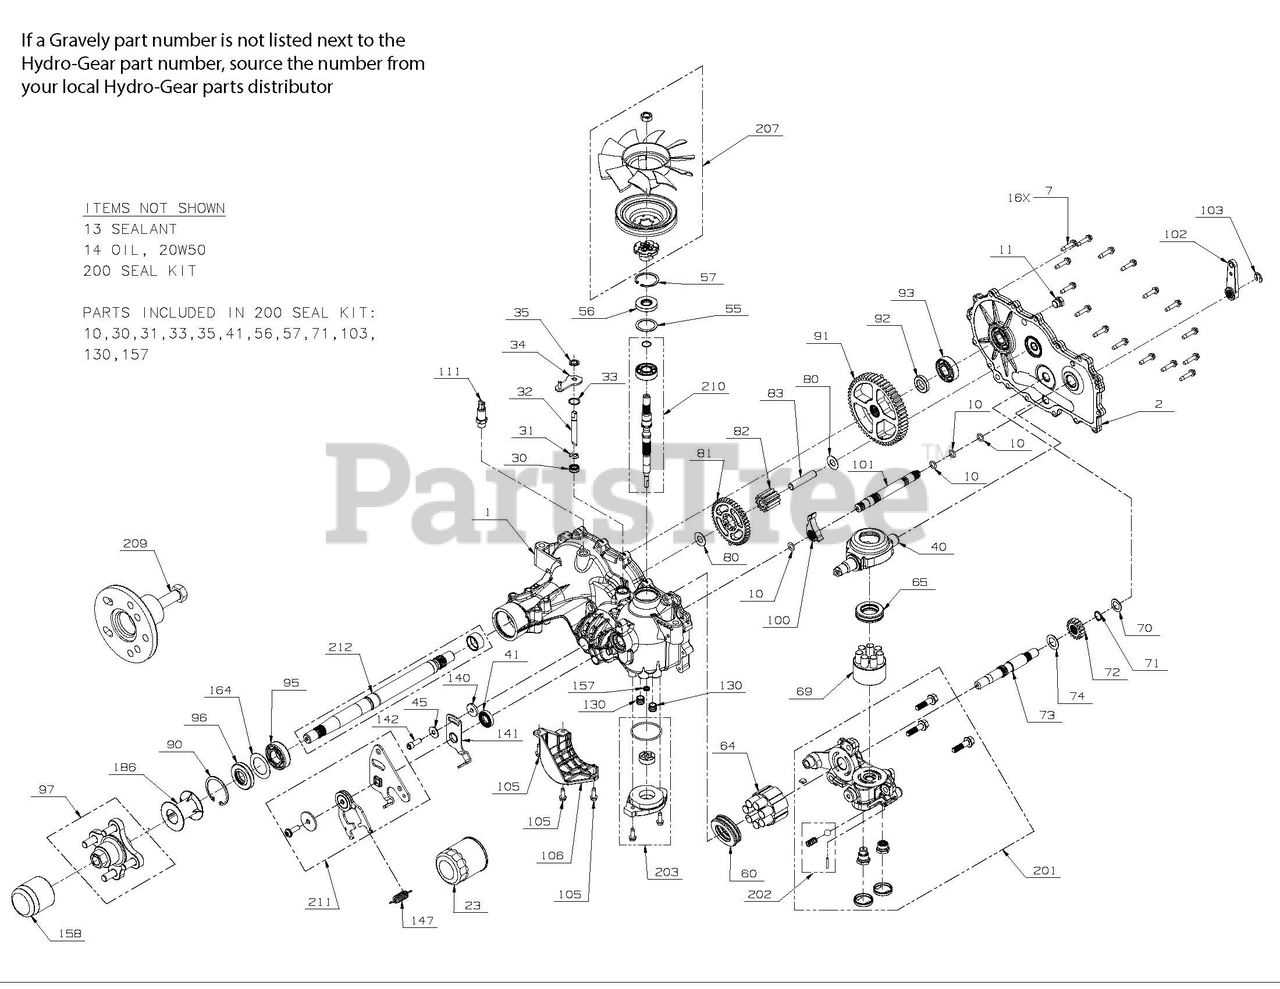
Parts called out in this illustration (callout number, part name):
7	SCREW, HEX WASHER
13	TUBE, SEALANT
23	FILTER, SPIN-ON 2.6 X 3.0
30	SEAL, LIP .375 X .75 X .25
31	RING, RETAINING EXTERNAL .375
33	RING, RETAINING .750, INTERNAL
34	ARM, BYPASS
35	RING, RETAINING .375 EXTERNAL
40	SWASHPLATE, TRUNNION
41	SEAL, LIP 18 X 32 X 7
45	WASHER FLAT .34 X .88 X .06
55	WASHER, FLAT 1.23 X 1.57 X .04
56	SEAL, LIP 17 x 40 x 7
57	RING RETAINING INTERNAL
60	BEARING, THRUST 35 x 62 x 18
64	KIT, 16cc CYLINDER BLOCK ASSEMBLY
65	BEARING, THRUST 30 x 52 x 13
69	KIT, BLOCK 7 PISTION
70	WASHER, .63 X 1.00 X .05 FLAT
71	RETAINING RING, MOTOR SHAFT
74	WASHER, .71 X 1.16 X .04 FLAT
80	WASHER, .51 X 1.00 X .03 FLAT
83	PIN, JACKSHAFT
90	RING, RETAINING 2.25 INTERNAL
95	BEARING, BALL 6205R-1 25.4 x 52 x 15
96	SEAL, LIP, TC4, 1.0 X 2.06 X .38
97	KIT, HUB 4 BOLT
105	SCREW, HEX WASHER 1/4-20 X .75
106	GUARD, FILTER, RH
111	KIT, FITTING 1/2 BEADED 9/16 SAE
140	SPACER 0.320 ID X 1.005 OD X 0.1495 -THK
141	ARM, NEUTRAL RIGHT
142	SHCS 5/16-24 x 7/8
147	SPRING, EXTENSION
200	KIT, SEAL, ZT-2800
203	KIT, CHARGE
207	KIT, FAN/PULLEY
209	KIT, HUB PULLER
210	KIT, INPUT SHAFT
211	KIT, RTN CW
